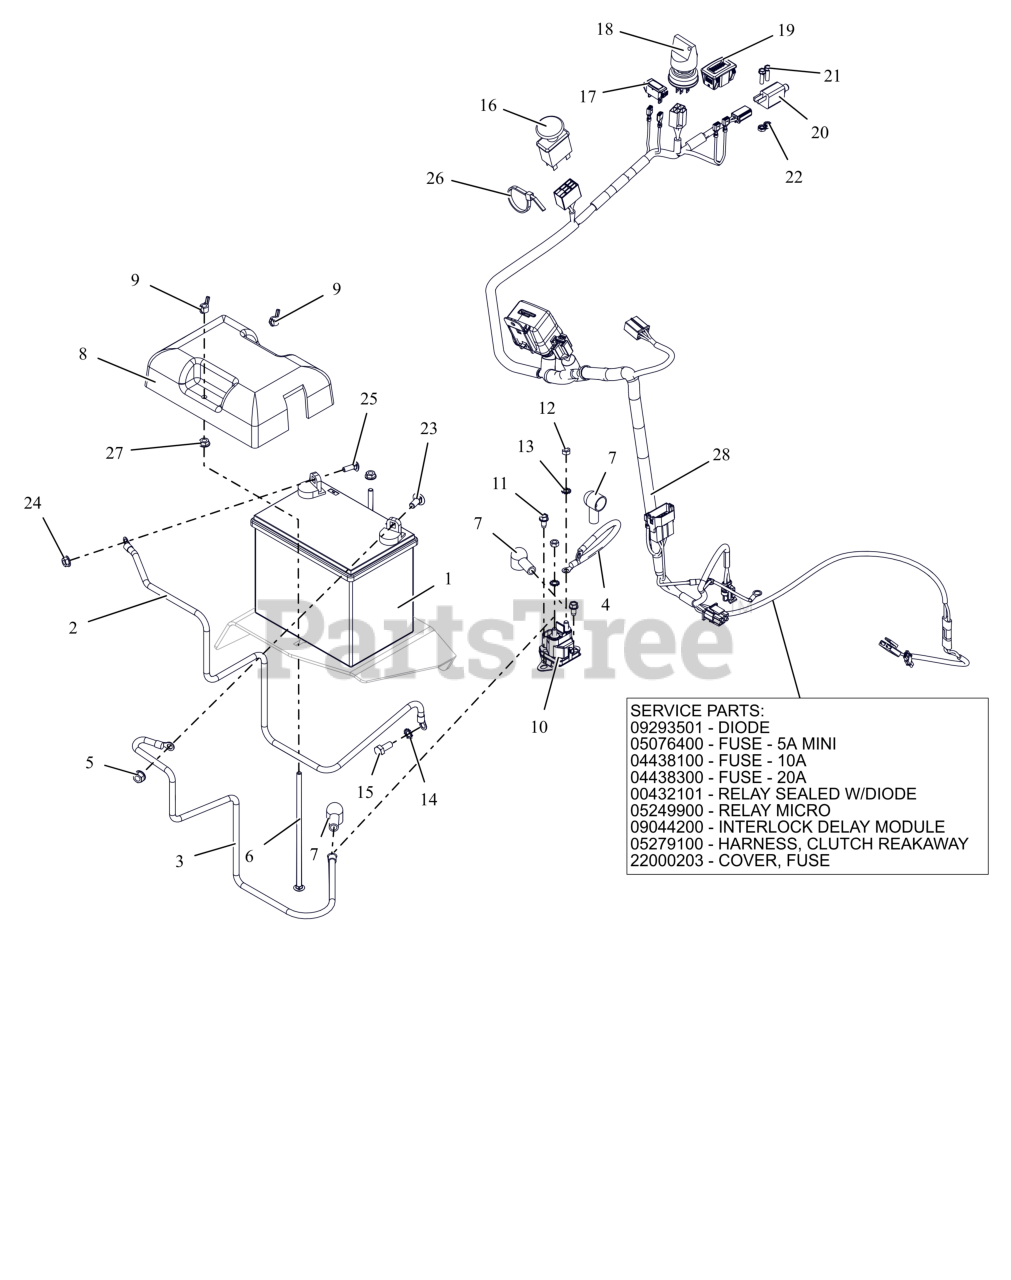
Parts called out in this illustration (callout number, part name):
1	BATTERY, 300 CCA 10U1L
2	CABLE- GROUND
3	CABLE- BATTERY
4	CABLE-POSITIVE BATTERY 9.00"
5	NUT,SPNLK-FLG .31-18 G5 ZCC
6	BTL,RHSN .250-20 X 7.5 G5 ZCC
7	BOOT, EYELET TERMINAL
8	COVER, BATTERY
9	NUT, LK-WING .25-20 ZCC
10	SOLENOID, STARTER (SEALED)
11	SCR-TAP .25-20X.50 HWH ZCC
12	NUT-STD M6-1.0 ZCC
13	WSHR,LK-EXT.262X.502X.026 ZCC
14	WSHR-LK-EXT 0.326X0.599X0.031 ZCC
15	BLT, HEX M8-1.25X20 G8.8 ZCC
16	SWITCH, CLUTCH
17	LIGHT, INDICATOR (RED)
18	SWITCH, IGNITION
19	HOUR METER
20	SWITCH- SINGLE POLE N.O.
21	BLT, HWH #10-24X.75 ZCC
22	NUT-KEPS 10-24
23	BLT,RHSN .31-18X.75 G5 ZCC
24	NUT-SPNLK-FLG .25-20 ZC120
25	BLT, RHSN .25-20X.750 G5 ZCC
26	CABLE TIE LG 5-1/2
27	NUT-LK-CTR-FLG .25-20 ZC120
28	HARNESS, MAIN-ECON PRO-STANCE
28	DIODE, CONNECTOR SHELL
28	FUSE, 5 AMP MINI-ATC
28	FUSE,10 AMP MINI-ATC
28	FUSE,20 AMP MINI ATC
28	RELAY,SEALED W/DIODE
28	RELAY,SPNO,SEALED,ISO280,RESIS
28	MODULE,INTERLOCK,DELAY, 1801
28	HARNESS, CLUTCH BREAKAWAY
28	COVER, FUSE
